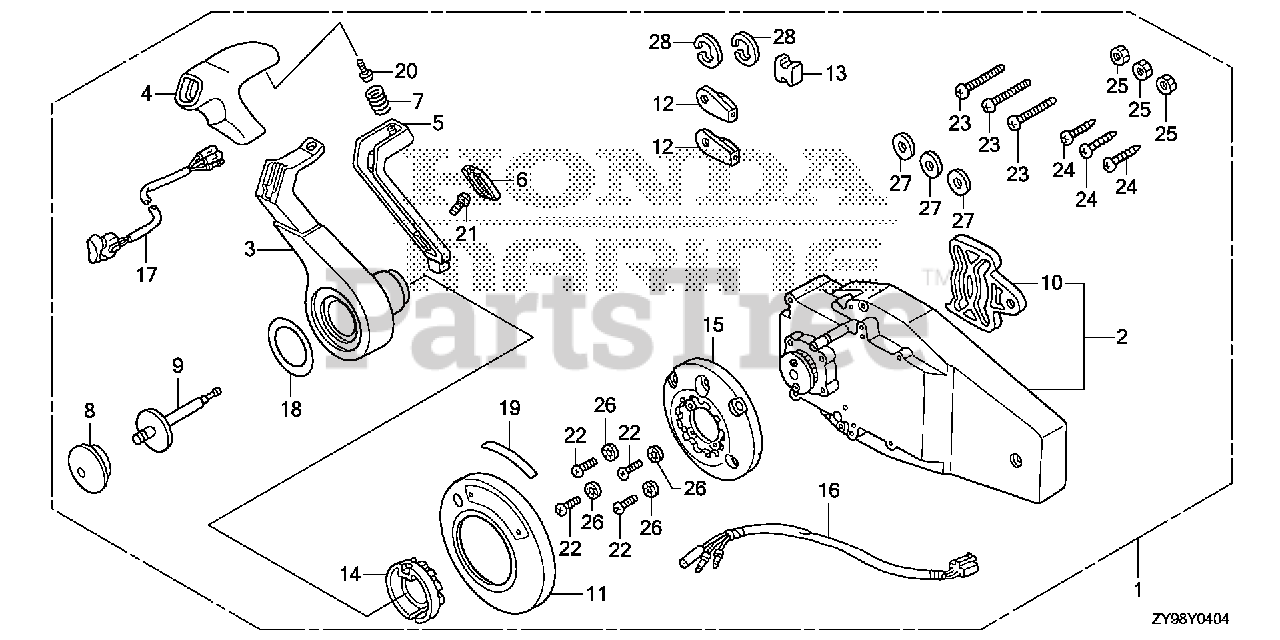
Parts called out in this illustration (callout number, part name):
1	BOX KIT, REMOTE CONTROL (FLUSH MOUNT)(R)
2	HOUSING ASSY., R. (INNER) (FLUSH MOUNT)
3	HANDLE, REMOTE CONTROL
4	COVER, GRIP
5	ARM, NEUTRAL LOCK
6	COVER, LOCK ARM
7	SPRING, NEUTRAL LOCK ARM
8	BUTTON, THROTTLE
9	SHAFT, THROTTLE BUTTON
10	PLATE, DWELL
11	COVER ASSY.
12	TERMINAL, CABLE
13	SPACER, CABLE CLAMP
14	HOLDER, NEUTRAL LOCK
15	BASE
16	SUB-HARNESS ASSY., POWER TRIM-TILT (C)
17	SWITCH ASSY., POWER TRIM-TILT (C)
18	MARK, HANDLE FLUSH MOUNT
19	MARK, FLUSH MOUNT
20	SCREW, PAN (5X16)
21	SCREW, TRUSS (4X12)
22	SCREW, PAN (5X30)
23	SCREW, PAN (6X35)
24	SCREW, TAPPING (6X30)
25	NUT, HEX. (6MM)
26	WASHER, LOCK (5MM)
27	WASHER, PLAIN (6MM)
28	E-RING (6MM)
